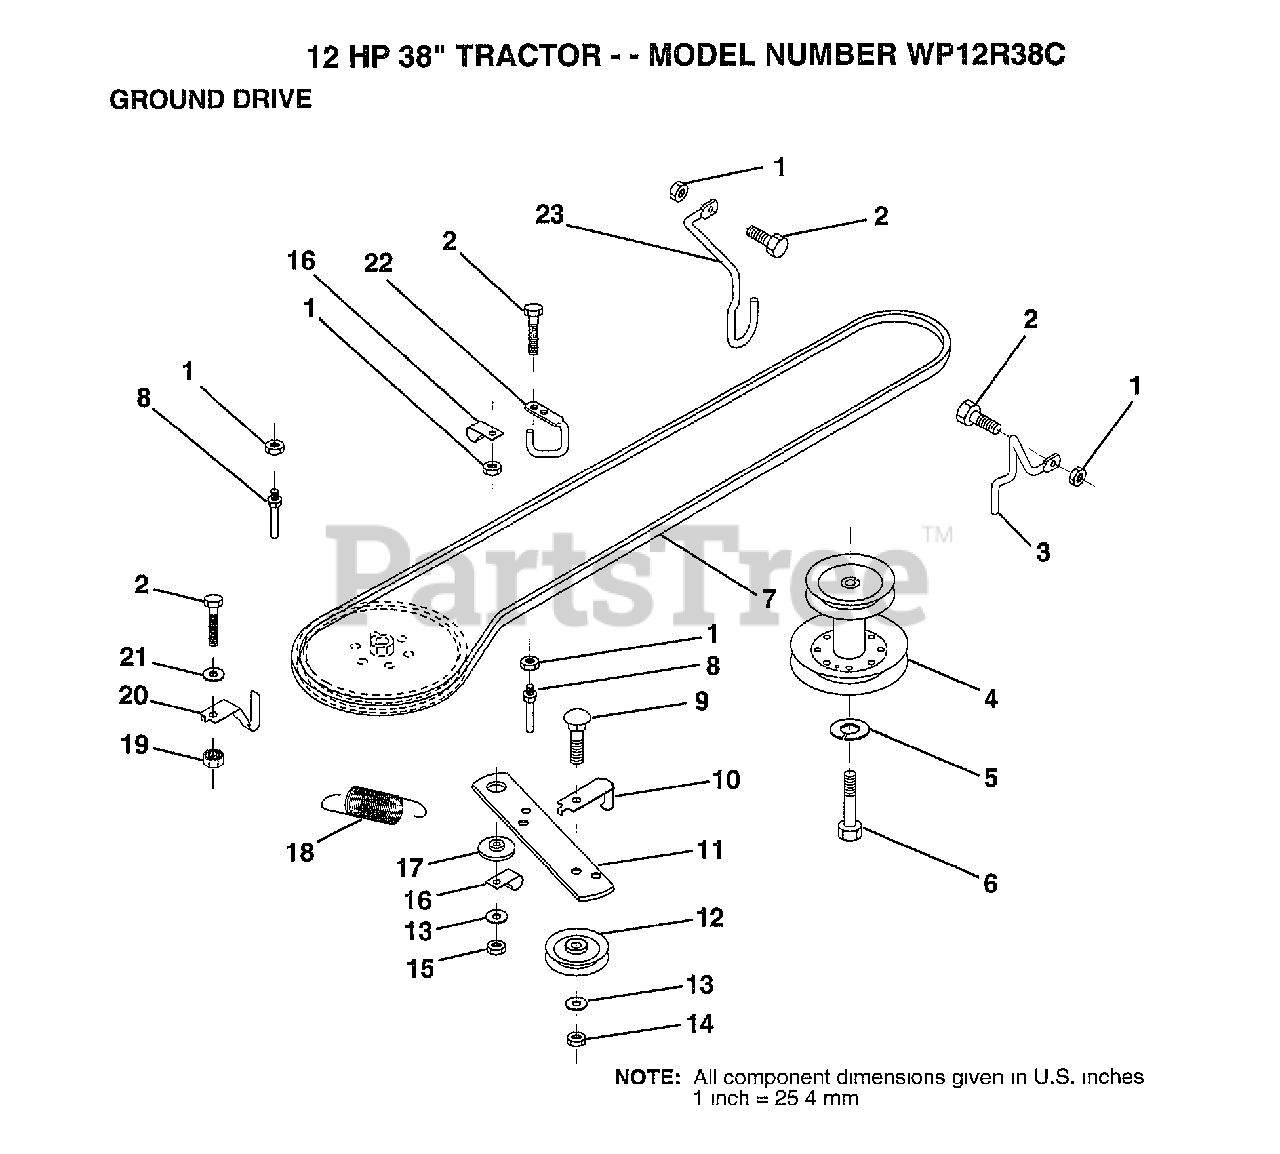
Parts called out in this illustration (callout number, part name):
1	NUT
2	BOLT
3	KEEPER.BELT.FRT.
4	PULLEY.ENGINE.LR
5	LOCKWASHER
6	HEX BOLT
7	BELT
8	"KEEPER,DRIVE BELT"
9	BOLT
10	"KEEP,IDLER DR BEL"
11	ARM IDLER CLUT GD
12	PULLEY.IDLER.FLAT
13	WASHER
14	LOCKNUT
15	NUT
16	CLIP INSULATOR
17	SPACER RETAINER
20	KEEPER.BELT.T/A
21	WASHER
22	"KEEPER,FRA DR BEL"
23	KEEPER.BELT.FRT.L
